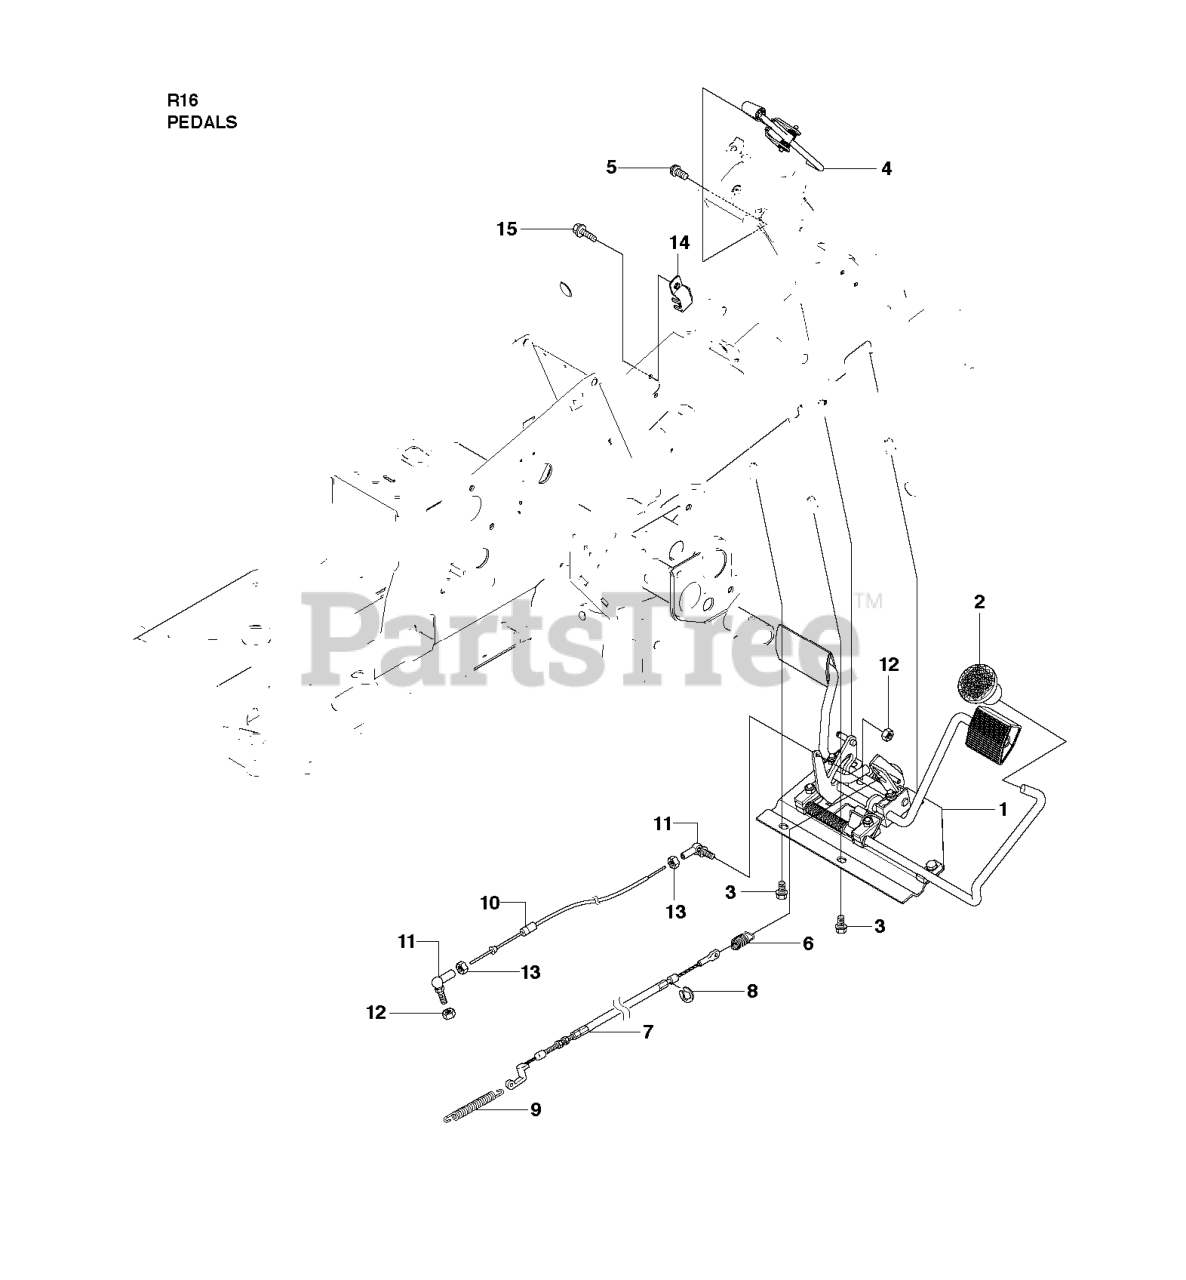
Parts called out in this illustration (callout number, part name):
1	PEDAL ASSEMBLY
2	KNOB
4	BRAKE LEVER ASSY
7	BRAKE WIRE
10	CONTROL CABLE
11	CONNECTOR
12	LOCKNUT M5
